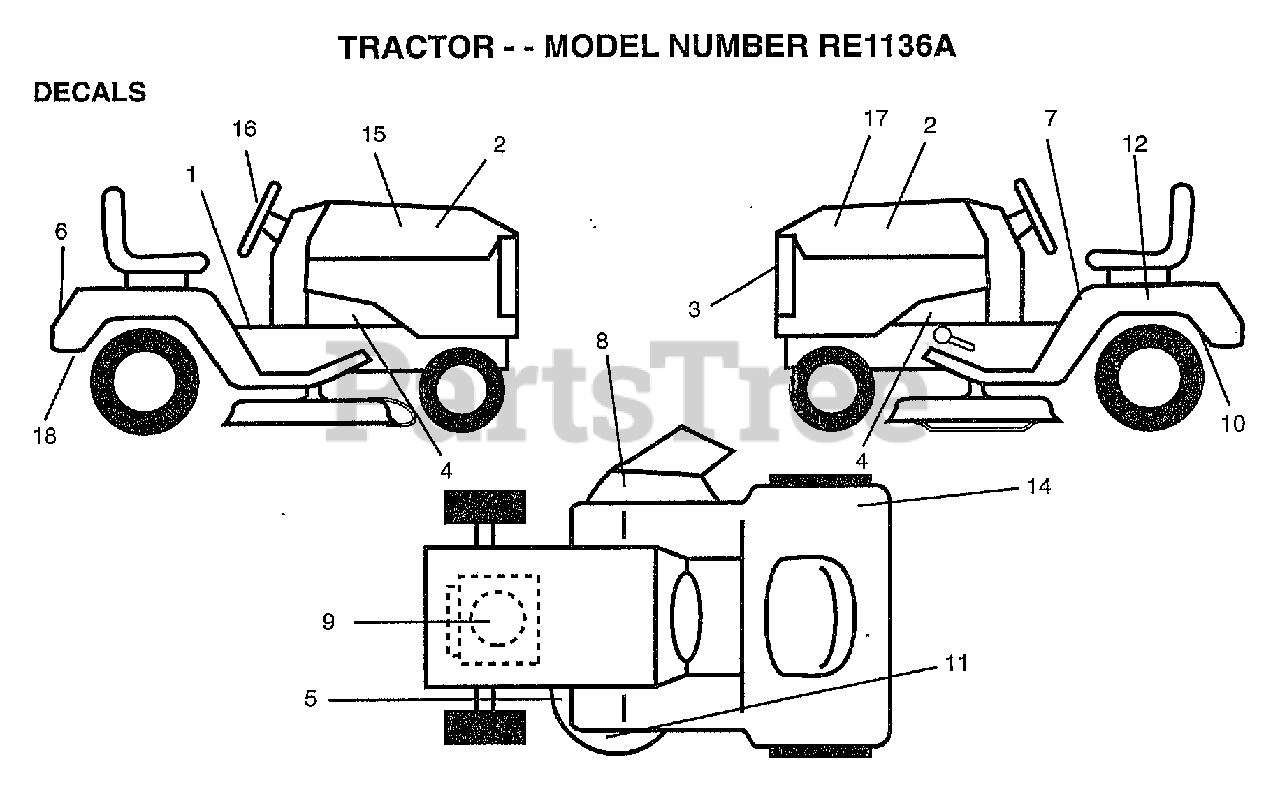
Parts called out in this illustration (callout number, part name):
1	DECAL CLUTCH/BRAK
2	DECAL.HOOD.INSERT
3	GRILL DECAL
4	"DECAL CHASSIS,HOT"
5	DECAL.V.BELT
6	FENDER DECAL
7	DECAL.READ.O.MANU
8	DECAL.DANGER.CUTF
10	DECAL.DRAWBAR.LDL
12	DECAL.BATRY.3-3908
15	DECAL HD RLY RH
16	"DECAL,STR WHL"
17	DECAL HD RLY LH
18	DECAL.EURO.ST.CE.
